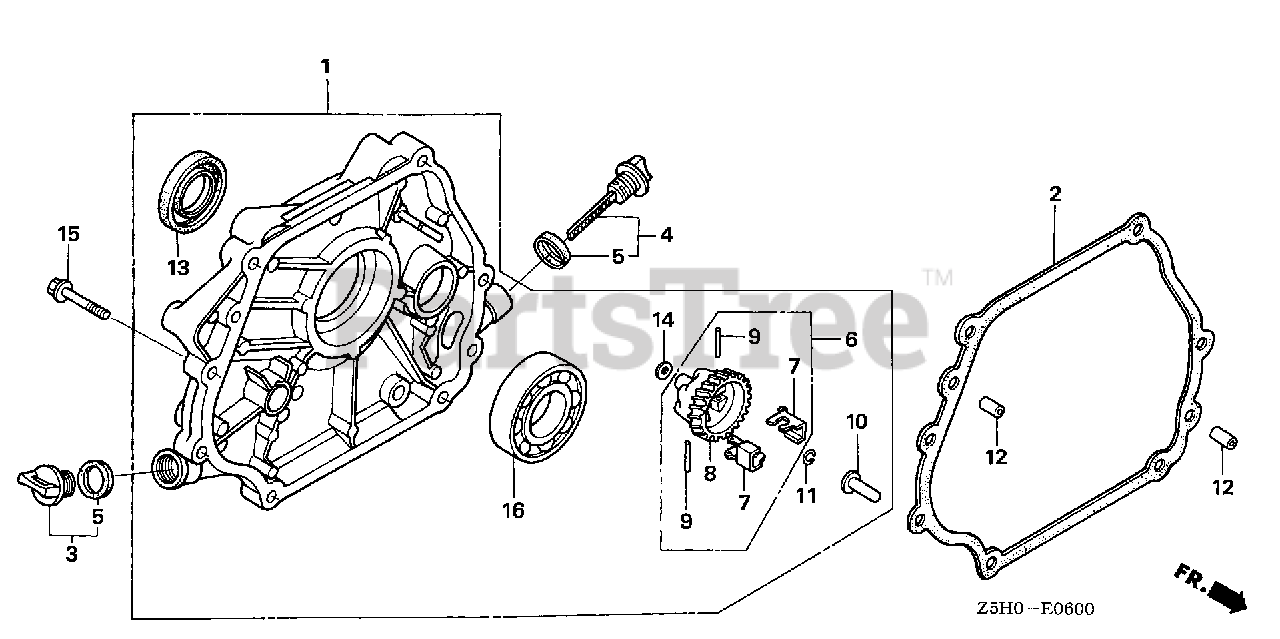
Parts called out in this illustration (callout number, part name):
1	COVER ASSY., CRANKCASE
2	GASKET, CASE COVER
3	CAP ASSY., OIL FILLER
4	CAP ASSY., OIL FILLER
5	GASKET, OIL FILLER CAP
6	GOVERNOR ASSY.
7	WEIGHT, GOVERNOR
8	HOLDER, GOVERNOR WEIGHT
9	PIN, GOVERNOR WEIGHT
10	SLIDER, GOVERNOR
11	CLIP, GOVERNOR HOLDER
12	PIN, DOWEL (8X12)
13	OIL SEAL (30X46X8)
14	WASHER, PLAIN (6MM)
15	BOLT, FLANGE (8X35)
16	BEARING, RADIAL BALL (6206)
